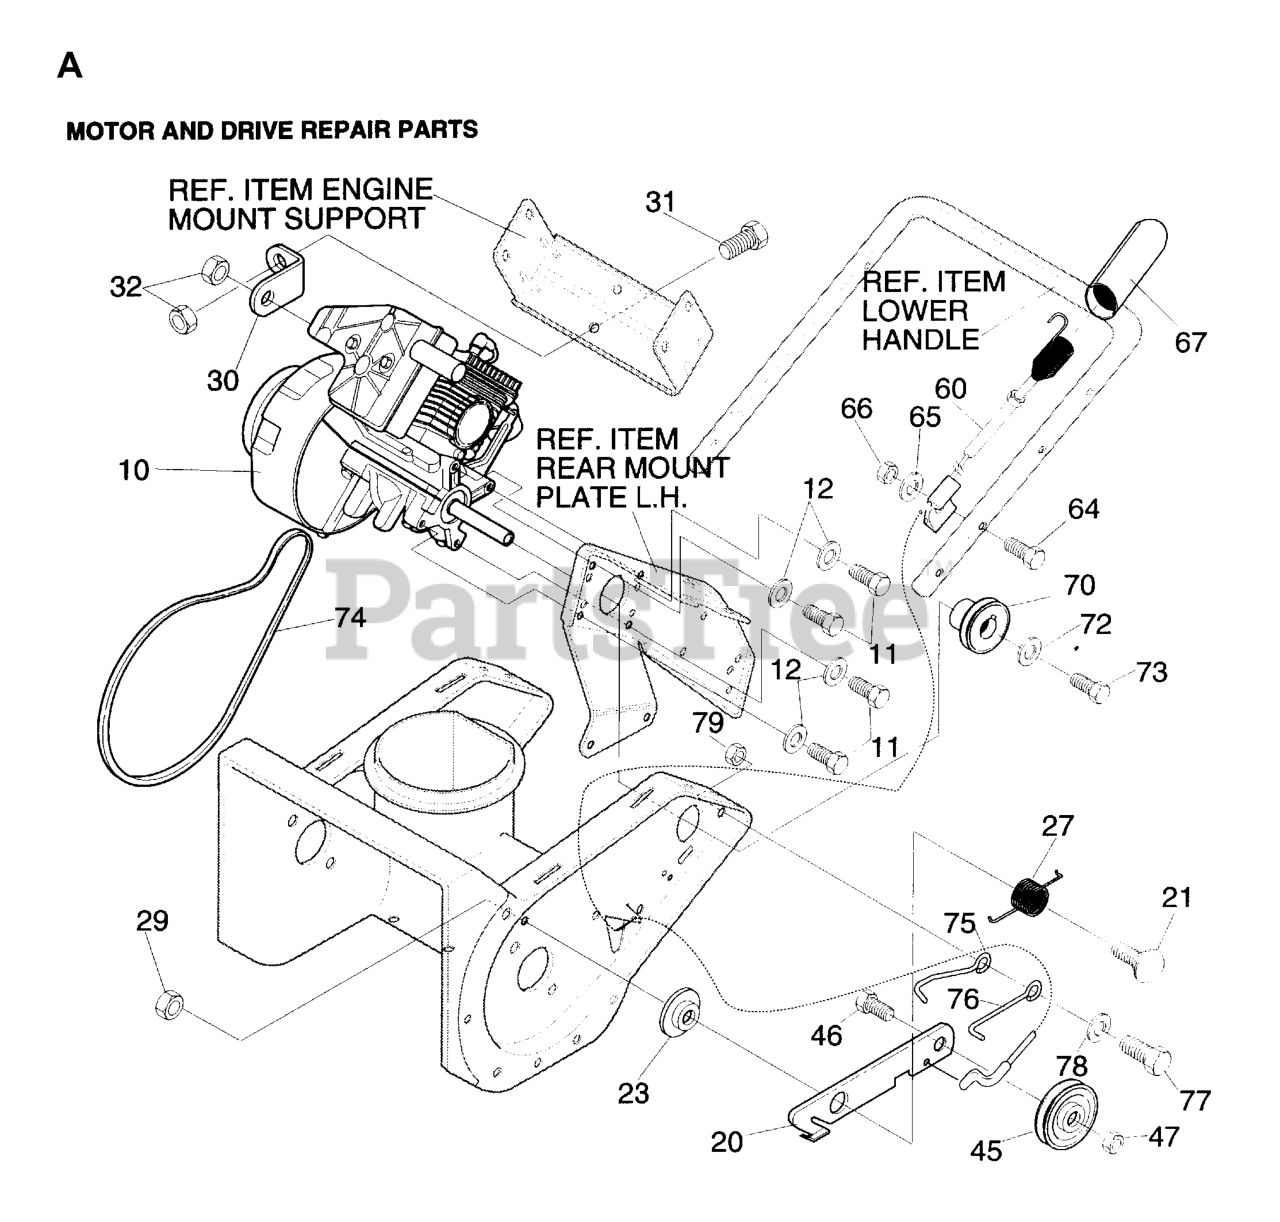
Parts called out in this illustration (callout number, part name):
12	WASHER
29	NUT.HEX.3/8-16UNC
32	NUT
46	BOLT
47	NUT.HEX.3/8-16UNC
64	Bolt Hex Fin 1/4-20 Unc x 1-1/2
65	WASHER
66	NUT.CROWNLOCK.1/4
72	WASHER - 25X8.5X2.3
75	BELT GUIDE
76	BELT GUIDE
78	WASHER
